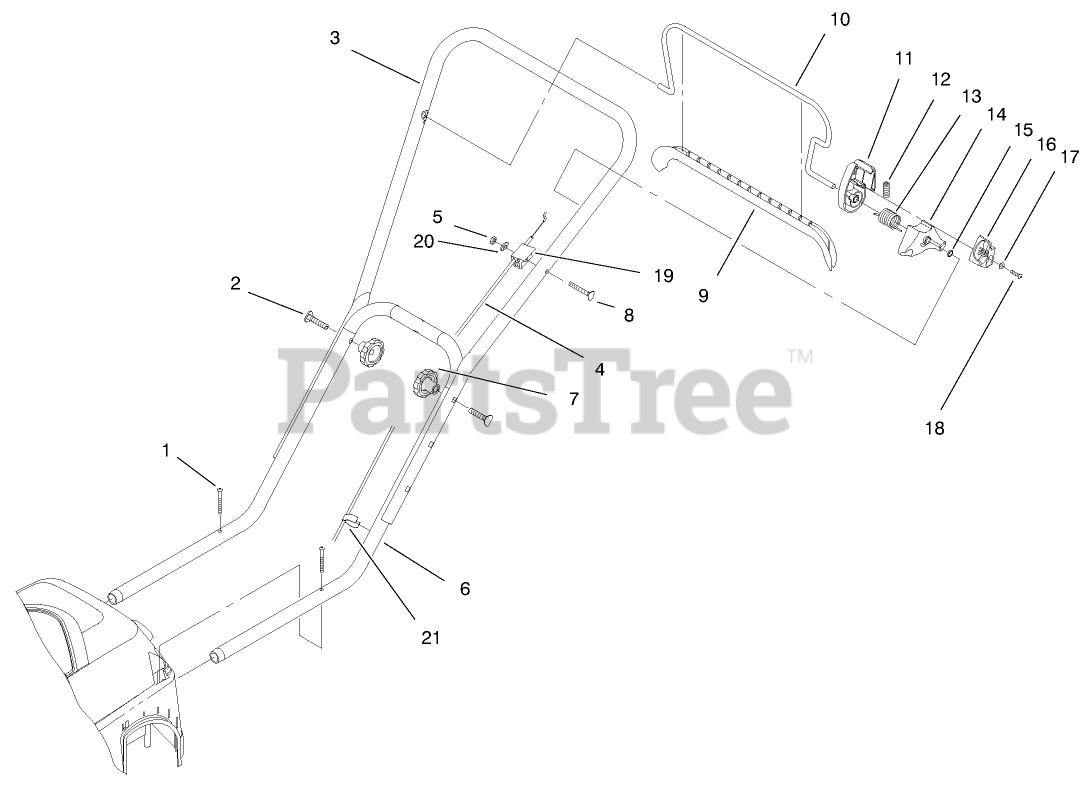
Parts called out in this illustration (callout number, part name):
1	SCREW-PPH
2	SCREW-HANDLE
3	Handle-Upper
4	CABLE - CONTROL
5	NUT-HEX
6	Handle-Lower
8	SCREW-HANDLE
9	COVER - BAIL
11	HOUSING - BAIL
12	SPRING - COMPRESSION
13	SPRING - BAIL
15	NUT - PUSH
16	SLIDE
17	WASHER - FLAT
18	SCREW-PPH
19	SUPPORT - CABLE
20	WASHER-FLAT
21	CLIP - CABLE
